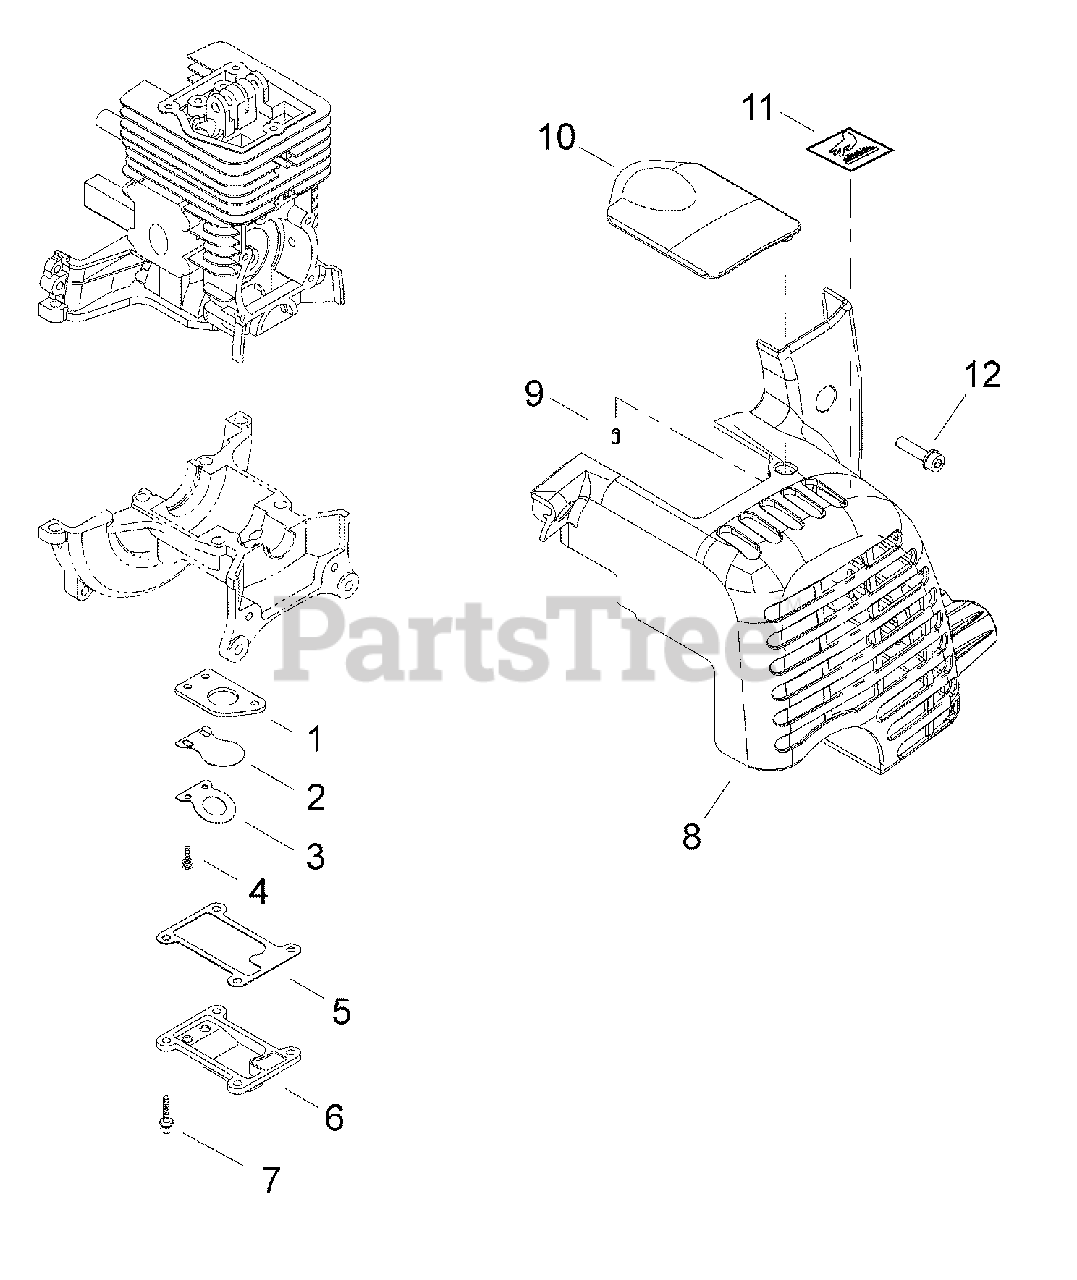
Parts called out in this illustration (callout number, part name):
1	PLATE, REED BACKING
2	VALVE, REED
3	STOP, REED VALVE
4	SCREW - 3X10
5	GASKET, REED VALVE
6	COVER, REED VALVE
7	SCREW - 4X12
8	COVER, ENGINE
9	PIN - 4X8
10	COVER, SPARK PLUG
11	LABEL - CAUTION
12	BOLT - 5X20
